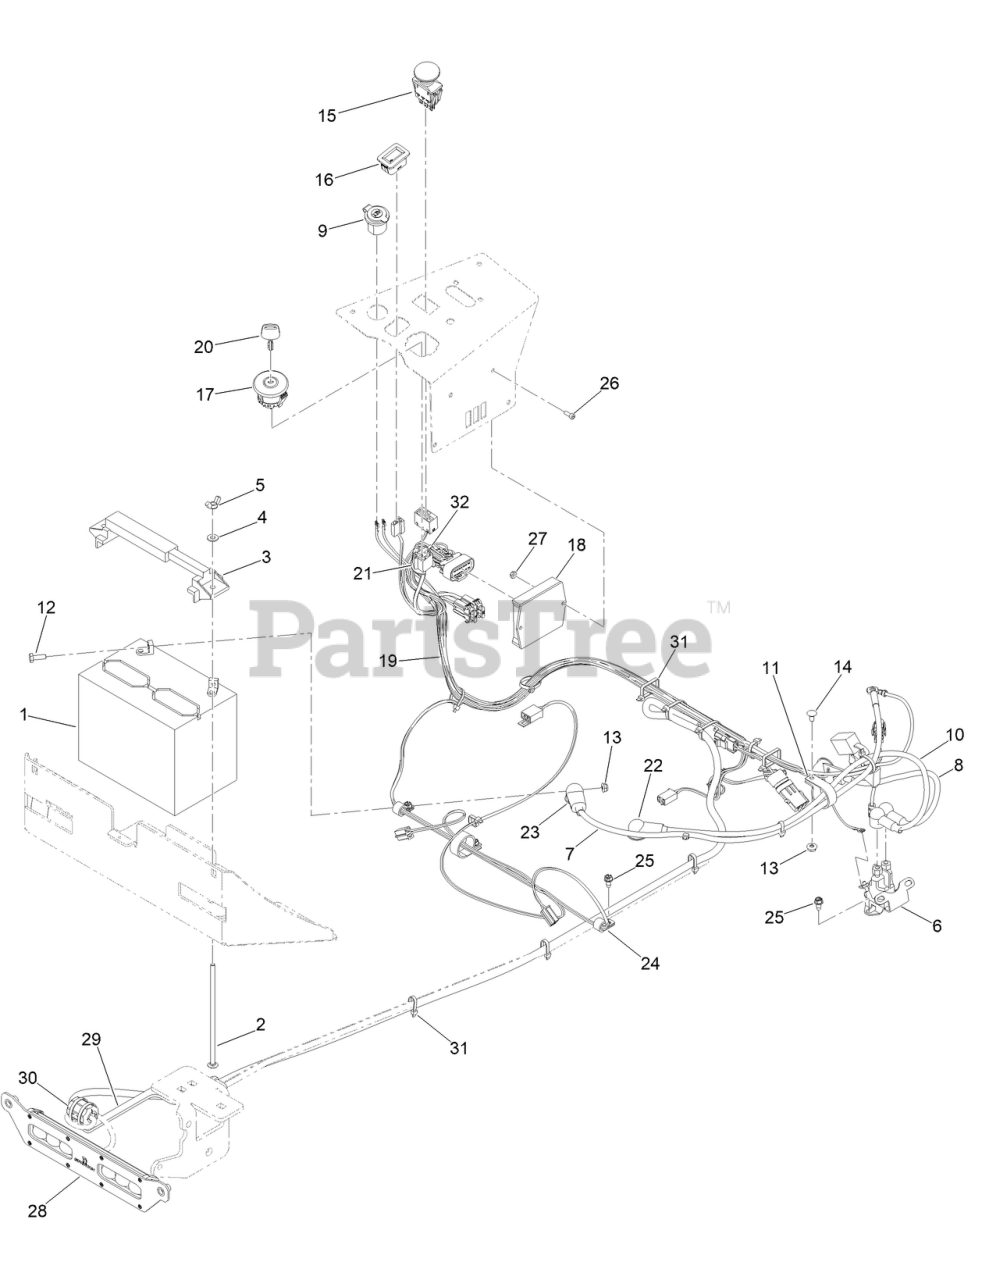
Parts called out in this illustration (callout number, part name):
1	12 VOLT START BATTERY 300CCA
2	1/4-20 X 7 CARRIAGE BOLT ZINC
3	BATTERY HOLD DOWN
4	WASHER-FLAT
5	NUT-WING
6	HEAVY DUTY START SOLENOID
7	MWR NEGATIVE CABLE 28
8	MWR START WIRE 12
9	12 VOLT AUXILLIARY PLUG
10	MWR POSITIVE BATTERY CABLE 25IN
11	1-1/4IN CUSHIONED LOOP CLAMP BLACK
12	SCREW-HH
13	1/4-20 HEX FLANGE NUT
14	SCREW-CARR
15	PTO SWITCH
16	HOUR METER
17	IGNITION SWITCH
18	INTERLOCK MODULE
19	BS 27HP/KAW 726CC RT PRO TTQ HRNS
20	2023 MWR KEY
21	MWR KEYSWITCH JUMPER HARNESS
22	3.15 LGTH STRAIGHT INSUL TERM COVER RED
23	STRAIGHT INSULATING TERMINAL COVER
24	CLAMP-R
25	SCREW-HWH
26	10-24 X 1/2 SOCKET C/S 18-8 SS
27	NUT-LOCK
28	SPLIT BEAM W/NON-LIGHTD HELMET LIGHT BAR
29	FAIR-RITE BRACKET PAINTED
30	FAIR-RITE ROUND CABLE SNAP-IT SIZE B
31	TIE-CABLE
32	6IN (40 LB) CABLE TIE NYLON UV
